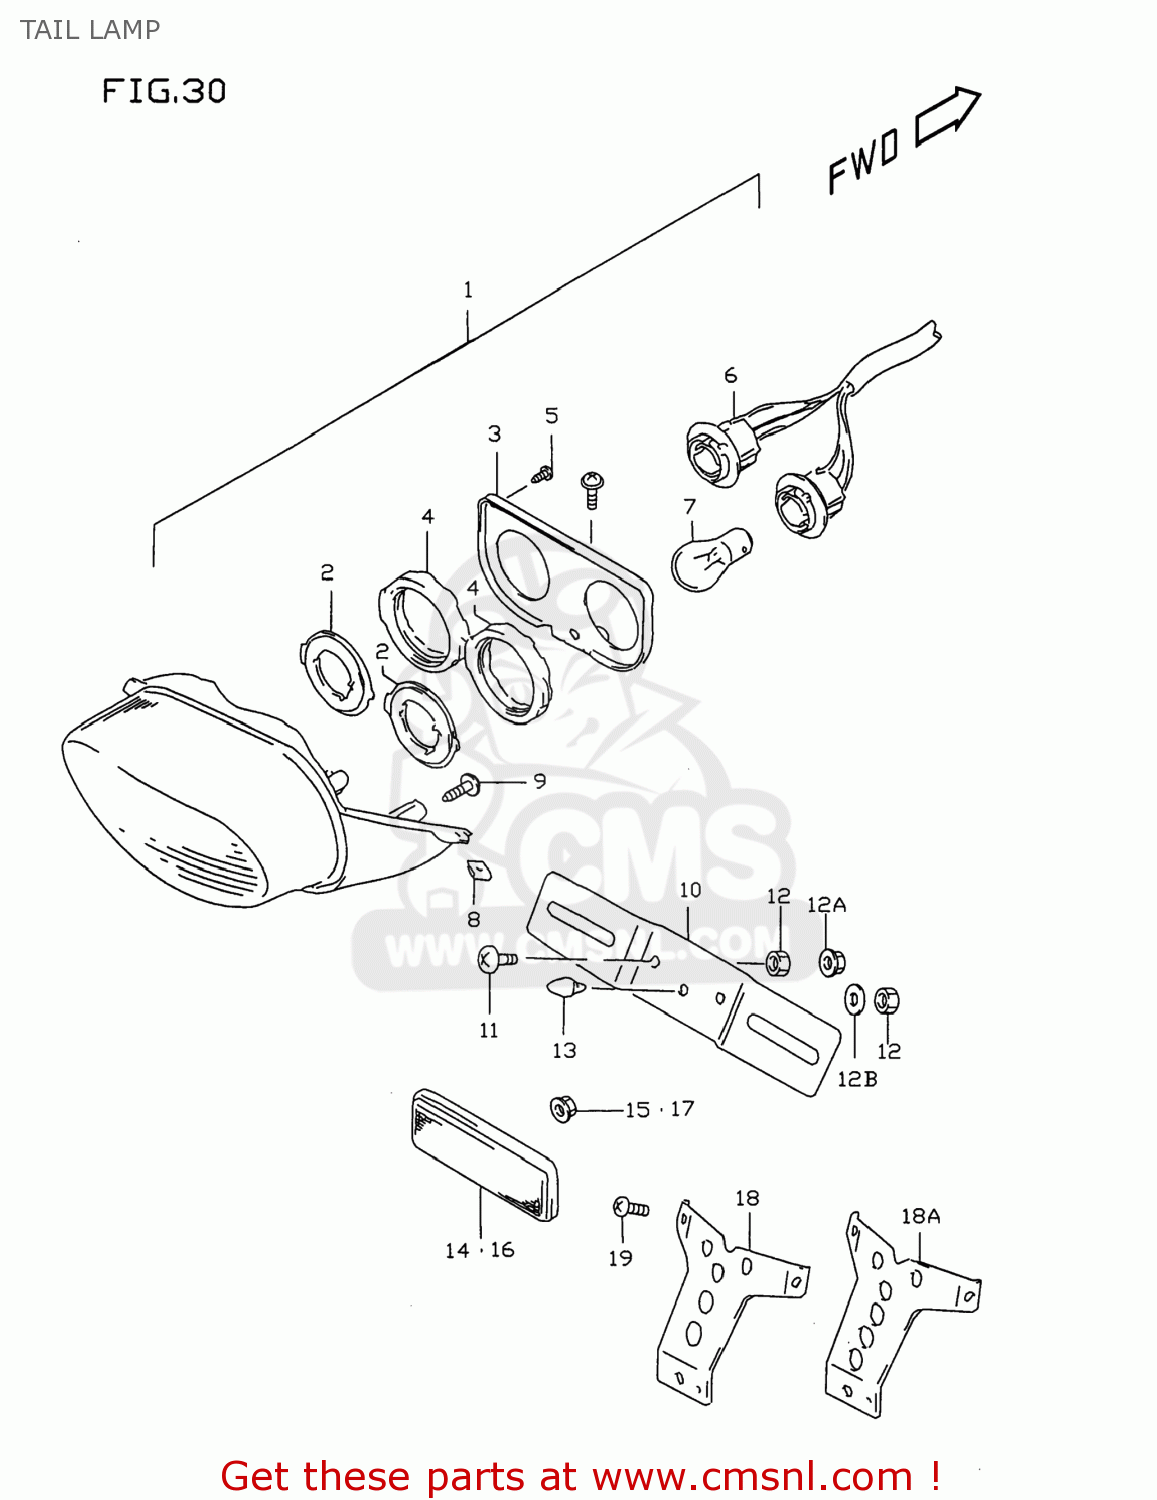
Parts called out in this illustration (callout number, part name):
1	LAMP ASSY,RR COMBINATION
2	PLATE NO.1
3	PLATE NO.2
4	CUSHION
5	SCREW
6	SOCKET & CORD
7	BULB(12V21/5W)
8	NUT
9	SCREW
10	BRACKET,LICENSE PLATE
11	SCREW 6X12
12	NUT 6MM
12A	NUT
12B	WASHER(6.5X20X1.2)
13	CUSHION
14	REFLECTOR ASSY,RR
15	NUT
16	REFLECTOR ASSY,RR
17	NUT
18	BRACKET,RR REFLECTOR
18A	BRACKET,RR REFLECTOR
19	SCREW(6X12)
